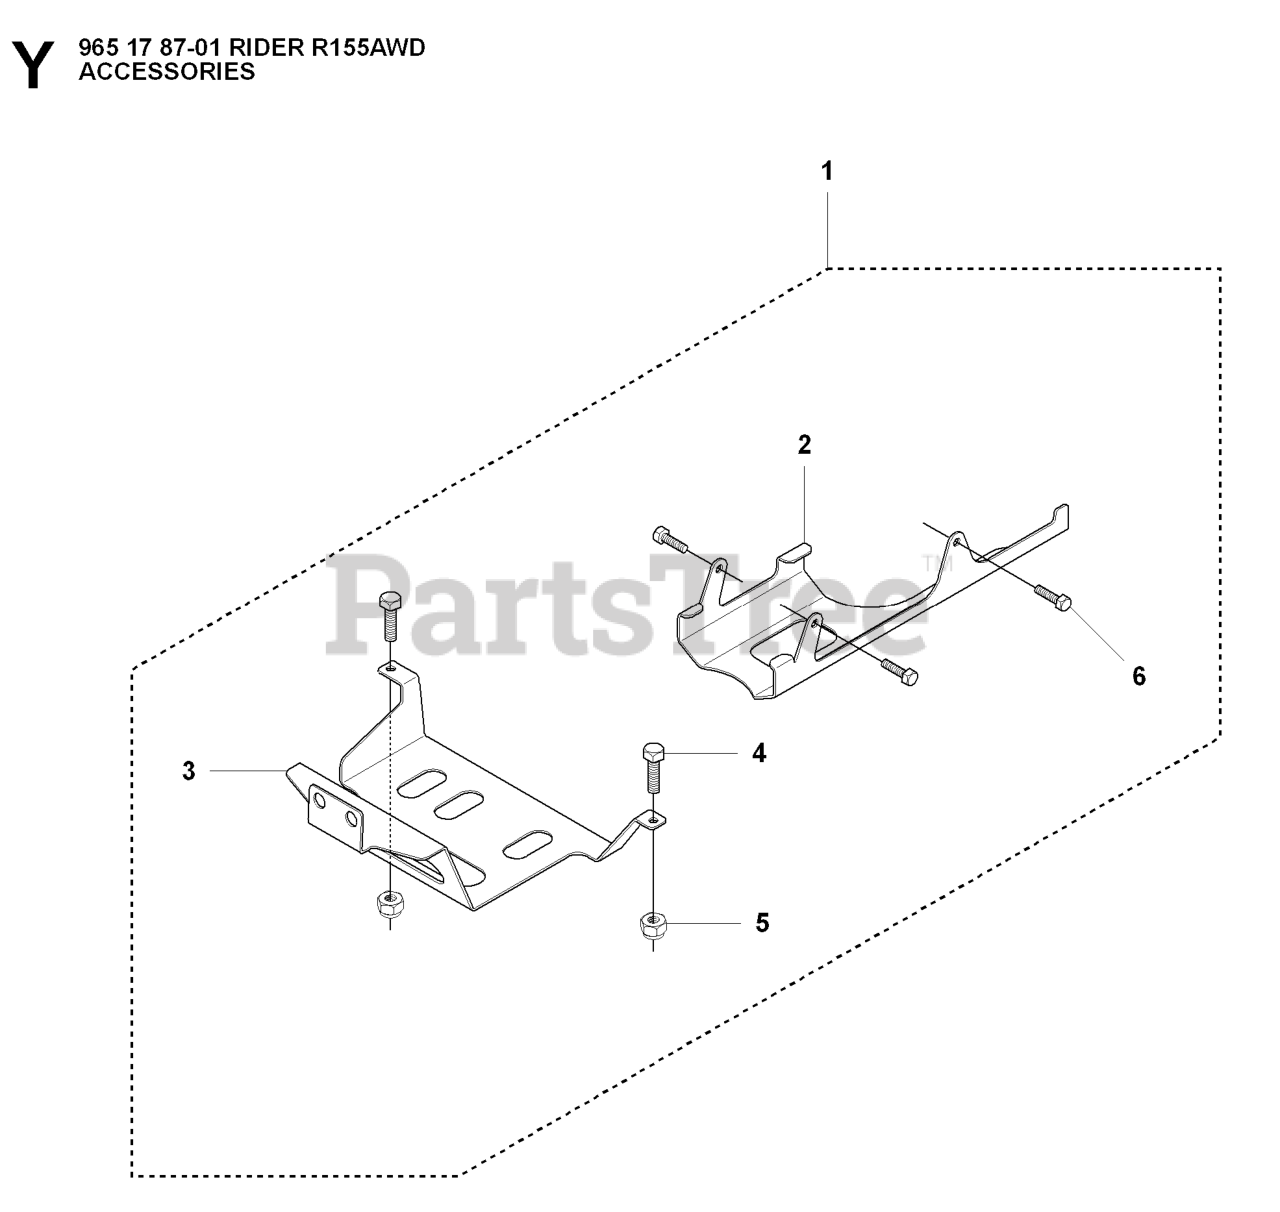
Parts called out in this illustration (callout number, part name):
1	AXLE PROTECTION KIT (R322T)
3	RP PROTECTION PLATE REAR
5	LOCKNUT M8
6	BOLT FLANGE - M8X16
